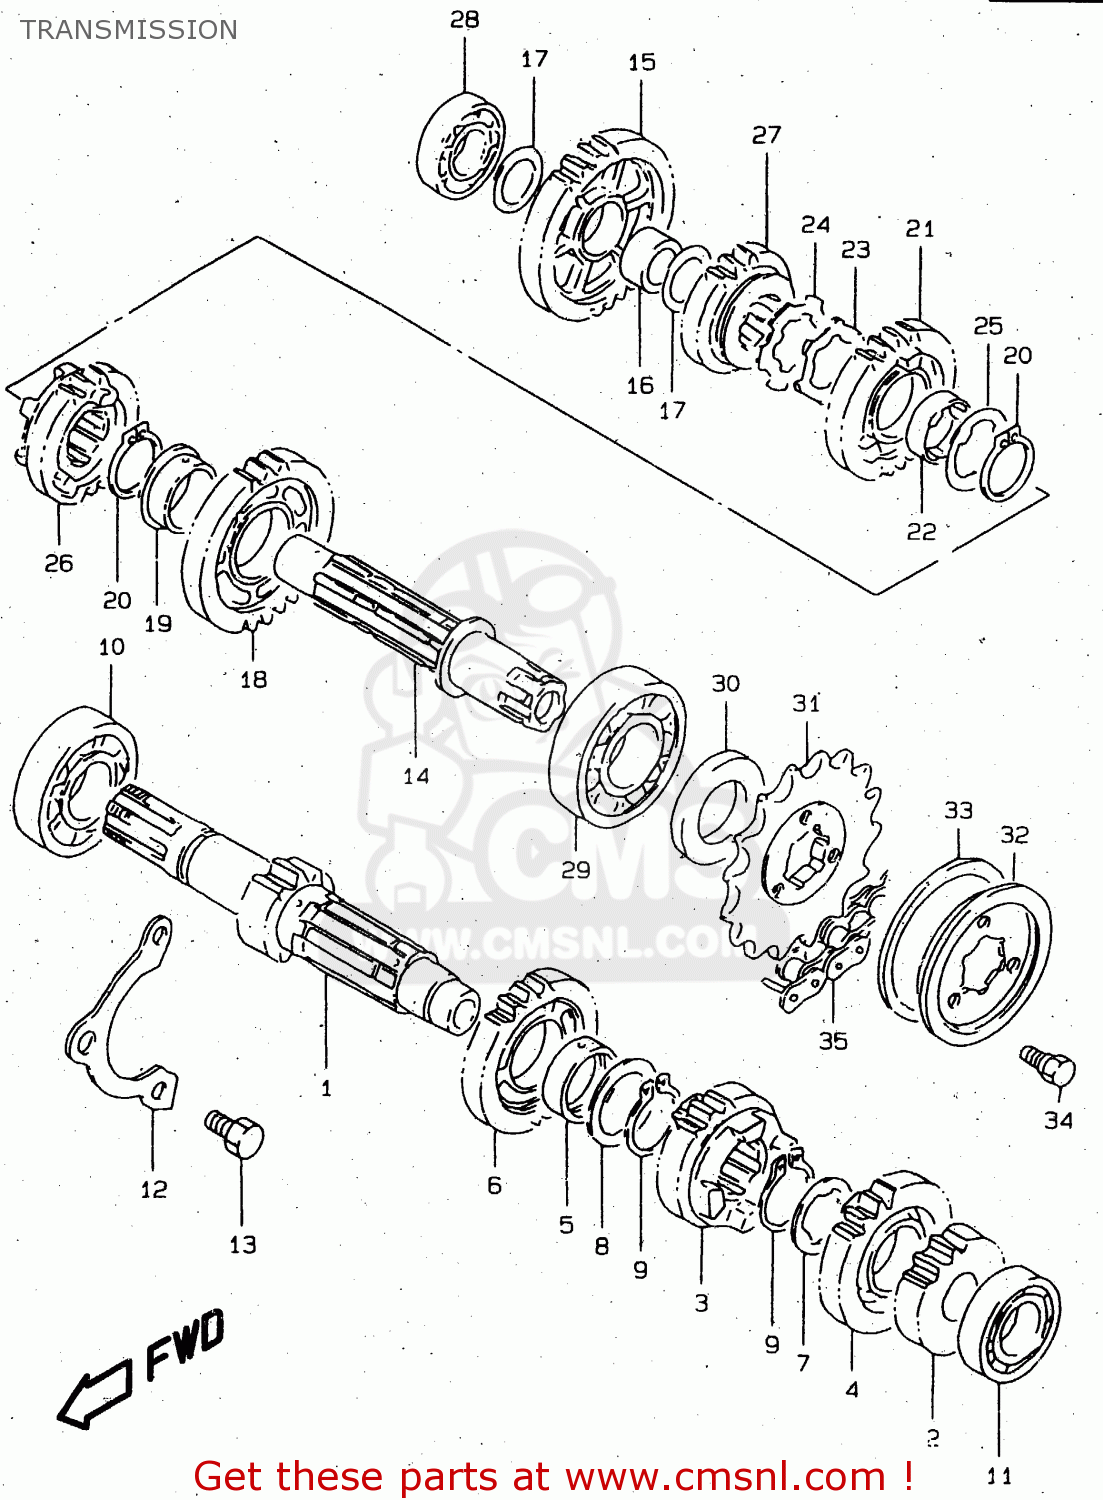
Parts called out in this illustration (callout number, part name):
1	SHAFT SET,CNTR
2	GEAR,2ND DRIVE
3	GEAR,THIRD DRIVE
4	GEAR,4TH DRIVE
5	BUSHING 25X29X10
6	GEAR,5TH DRIVE
7	WASHER,LOCK
8	WASHER
9	RING,SNAP
10	BEARING(22X56X16)
11	BEARING
12	RETAINER,CNTR SHAFT BEARING
13	BOLT
14	SHAFT,DRIVE
15	GEAR,1ST DRIVEN
16	BUSH(20X24X13)
17	WASHER
18	GEAR,2ND DRIVEN
19	BUSH
20	RING,SNAP
21	GEAR,3RD DRIVEN
22	BUSHING
23	WASHER
24	WASHER,LOCK
25	WASHER,LOCK
26	GEAR,4TH DRIVEN
27	GEAR,5TH DRIVEN
28	BEARING(20X42X12)
29	BALL BEARING 25X62X17
30	SEAL,OIL(25X44X7)
31	SPROCKET,ENGINE(15T)
32	PLATE,ENGINE SPROCKET
33	DAMPER,ENGINE SPROCKET
34	BOLT(6X13)
35	CHAIN,DRIVE(DID525V9,110L)
